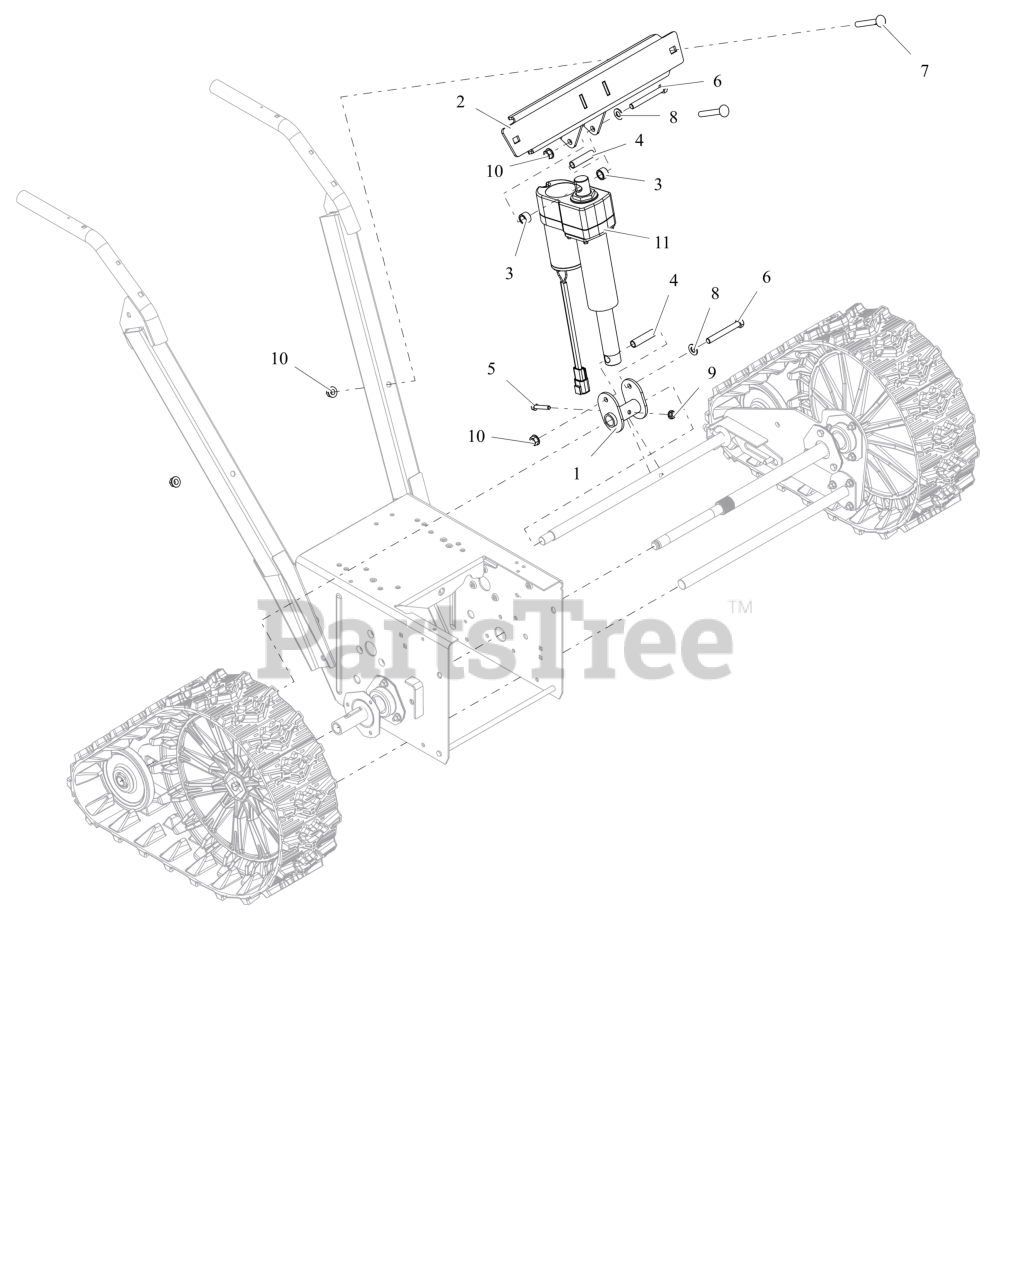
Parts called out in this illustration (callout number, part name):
1	WLDMT, REAR TRACK AXLE BRKT
2	WLDMT- LINEAR UPPER BRKT
3	BSHG-SLV .510X.751X.475
4	SPCR, WHEEL .385X.500X2.00
5	BLT, HEX .25-20X1.50 G5 ZCC
6	BLT, HEX .38-16X3.00 G5 ZCC
7	BLT, RHSN .38-16X2.75 G5 ZCC
8	WSHR, FLT .406X.812X.065 RAW
9	NUT-LK-CTR-FLG .25-20 ZC120
10	NUT-LK-CTR-FLG .375-16 GF ZCC
11	ACTUATOR, LINEAR
